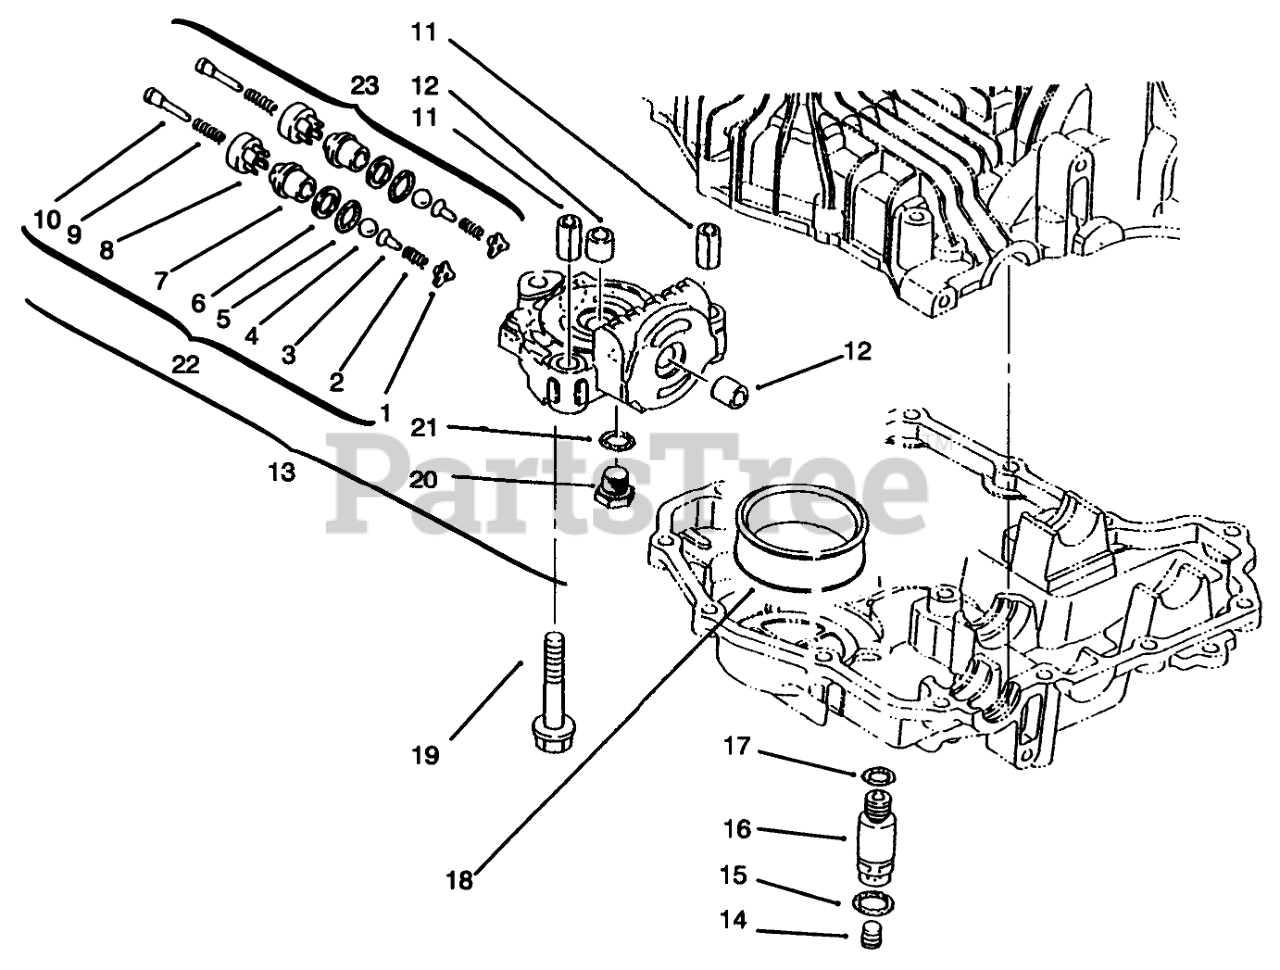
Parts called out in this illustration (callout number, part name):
1	Holder-Bypass
3	Holder-Ball
4	Ball
5	PACKING
6	Ring-Back Up
8	Valve B
10	Pin-Push
11	PIN-KNOCK
12	BUSHING
13	Case INC 11-12 & 20-23
15	PACKING
16	CONNECTOR
17	PACKING
18	FILTER
21	PACKING
22	ASM - VALVE A1 INC 1-10
23	ASM - VALVE A2
